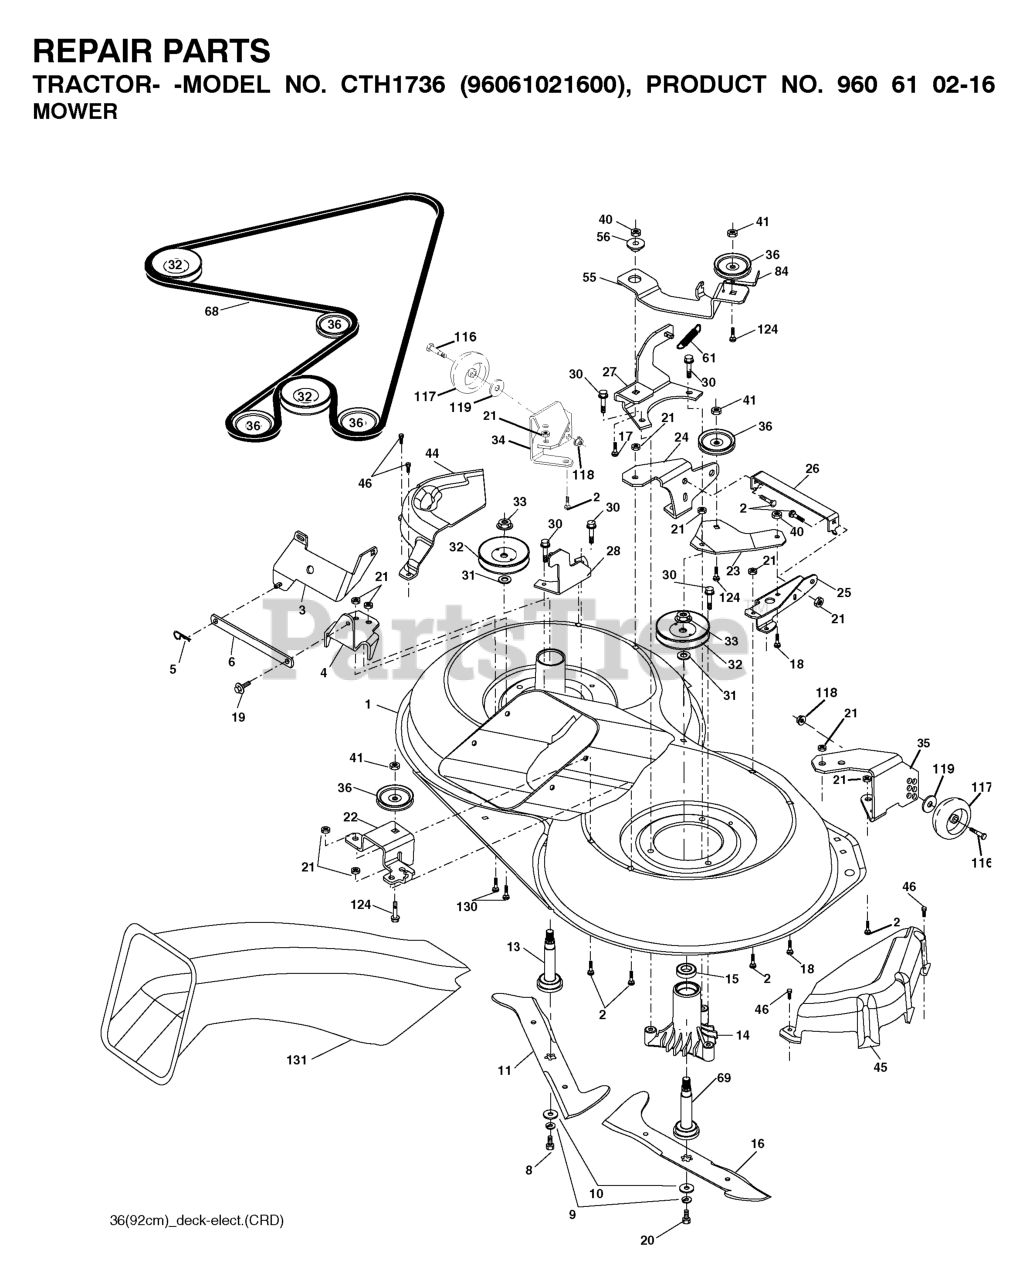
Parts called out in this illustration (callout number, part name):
2	RP BOLT 5/16-18 X3/4 ZN/YEL GR
5	RETAINER-SPRNG RB
6	BAR.SWAY.92.CRD
8	BOLT.3/8-24X1.25 GR8
9	LOCKWASHER
10	WASHER.BLADE
13	SHAFT ASM VENT
14	HOUSING.MANDREL.VENTED (MACHD)
17	BOLT.3/8-14X1.25
19	BOLT SHD 5/16-18
20	BOLT.3/8-24X1.25GR8. LHTHRD
21	LOCKNUT
26	SUPPORT
30	SCREW, WASHER HEAD
31	WASHER.SPACER.MANDREL
33	NUT.FLANGE.LOCK.TOP
36	PULLEY.IDLER.4.25
41	NUT LOCK FLG 3/8-16 UNC
45	COVER.MANDREL.RH.CRD
46	SCREW.1/4-20X5/8
55	ARM.IDLER.92 CRD.2006
56	SPACER.RETAINER.MOWER
61	SPRING
68	BELT.DRIVE.92CM.CRD.2006
69	SHAFT.ASM.W/LWR.BRG.RH.THREAD
84	KEEPER, BELT IDLER
116	BOLT.SHOULDER.3/8-16X3-5/8.
117	RP WHEEL. GUAGE RALLY
118	LOCKNUT
119	WASHER
124	BOLT.3/8-16X1.50
130	BOLT.CARR.SQNK.5/16-18UNC.X3/4
131	CHUTE BAGGER
